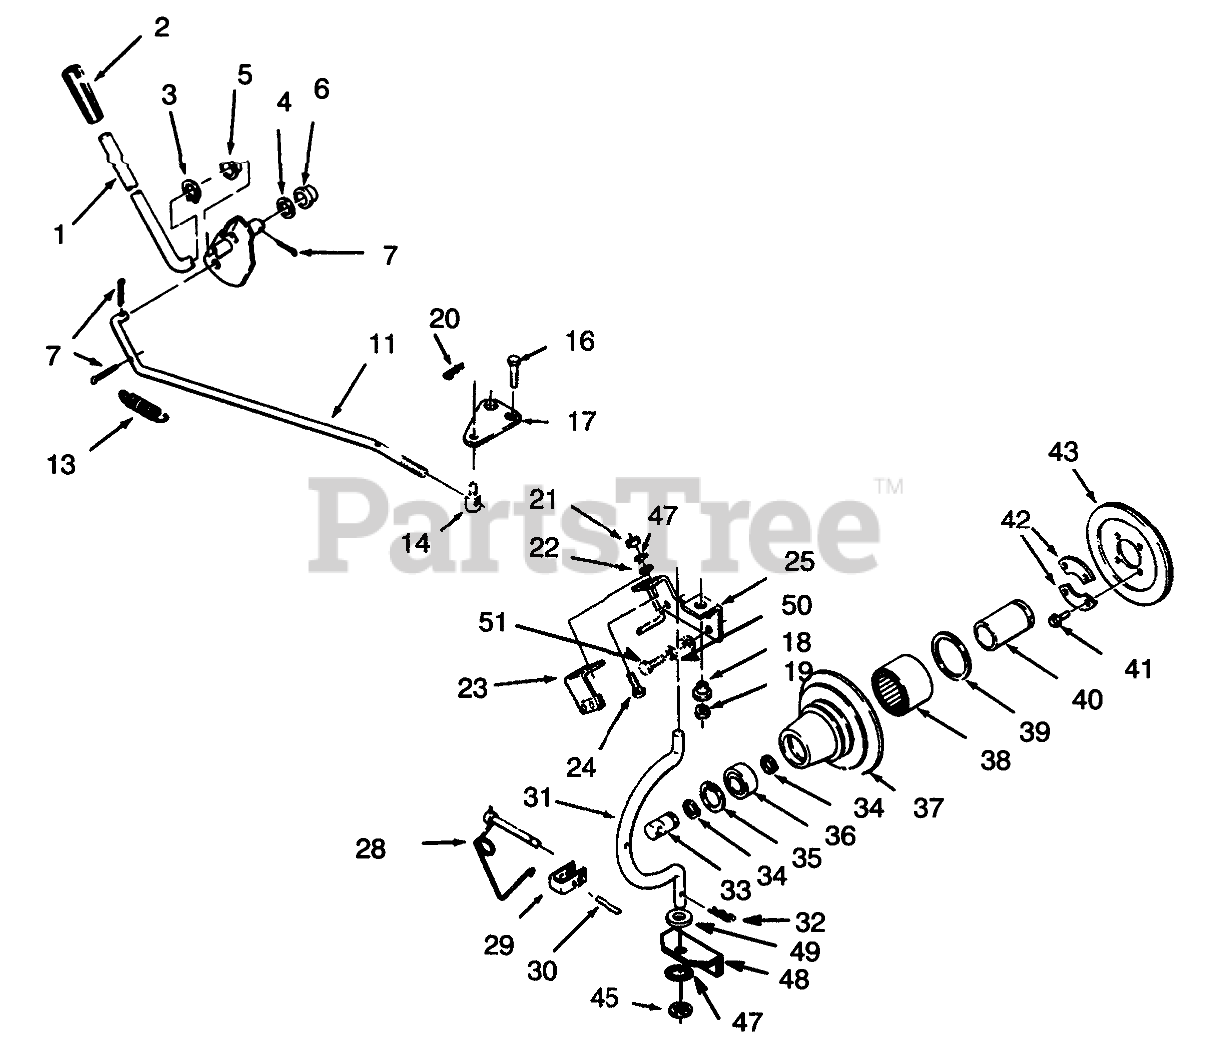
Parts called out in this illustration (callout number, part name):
1	ASSY PTO CLUTCH LEVE
2	GRIP
3	RING-EXT GRIP
4	SHIM-WASHER
5	BUSHING-NYLINER
6	NYLINER BUSHING
7	PIN-COTTER
11	ROD-PTO CLUTCH
13	SPRING
14	TRUNNION
16	SCREW-HH
17	PLATE
18	SPACER-LIFT LINK
19	NUT-LOCK, NI
20	Hairpin Cotter
21	NUT-JAM
22	WASHER-FLAT
23	ASM-Bracket
24	SCREW-CARR
25	Bracket-Engine
28	LOCKING PIN ASM
29	CLEVIS
31	ROD-HOUSING
32	Hairpin
33	SHAFT-PTO
34	Ring-Snap
35	RING-RETAINING
36	BEARING-BALL
37	Housing-Clutch
38	Seal
39	SEAL-OIL
40	RACE-BEARING
41	SCREW-HEX HD CAP
42	RETAINER
43	Facing-Clutch
45	RING-REINFORCED CIRC
47	WASHER-LOCK
48	Axle
49	WASHER-FLAT
50	WASHER-LOCK
51	SCREW-HH
